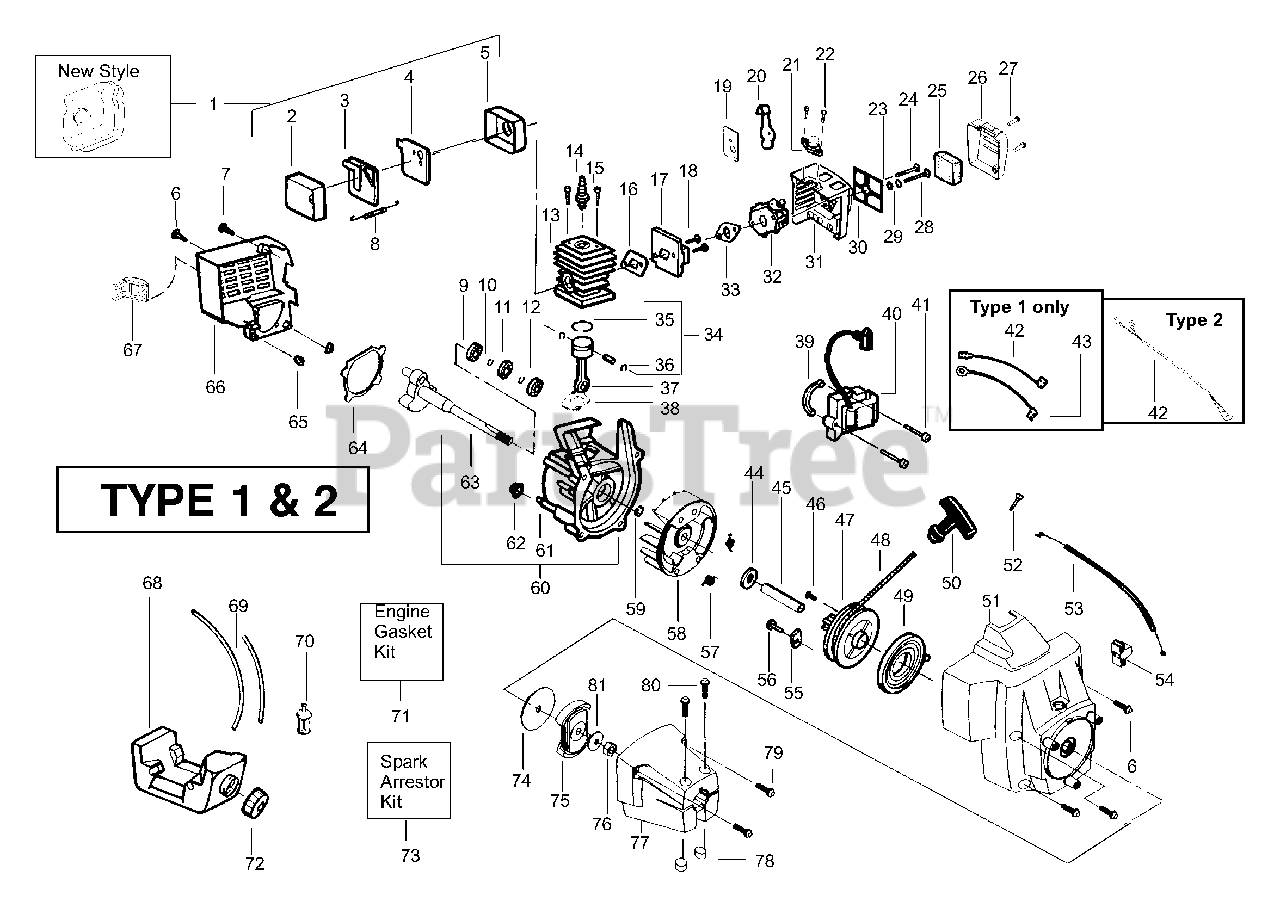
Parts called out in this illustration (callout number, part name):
1	Kit-Muffler Old Style
1	Kit-Muffler New Style
2	Muffler Cover
3	Muffler Baffle-Exit
4	Muffler Baffle-First
5	Muffler Body
6	Screw
8	Muffler Spring Old Style
8	Muffler Spring New Style
9	Inner Bearing
10	Retaining Ring-C'case
11	C'case Seal
12	Outer Bearing
13	Cylinder Kit
14	Spark Plug (RCJ-8Y)
16	Gasket-Cyl/Carb Adpt
17	Kit-Carb. Adaptor
19	Choke Plate
20	Choke Shutter
21	Assy-Purge Bulb
25	Air Filter Foam
26	Air Filter Cover
29	Choke Spacer
30	Filter Plate
32	Assy-Carburetor
33	Gasket-Carburetor
34	Kit-Piston
35	Ring-Piston
36	Piston Pin Retainer
37	assy-Connecting Rod
38	Gasket-Cylinder
39	Spacer-Ign. Module
40	Ignition Module
42	Assy-Lead Wire Old Style (type 1)
42	Assy-Lead Wire New Style (type 2)
43	Assy-Ground Wire Old Style (type 1 only)
45	Spacer-Flywheel
47	Starter Pulley
48	Rope Kit
49	Spring-Starter
50	Handle-Starter
51	Fan Housing Old Style (type 1)
51	Fan Housing New Style (type 2)
53	Assy-Throttle Cable
54	Kit-Switch
55	Retainer
57	Starter Spring
58	Assy-Flywheel
59	Retainer (C'shaft)
60	Assy-C'case & C'shaft
61	Assy-Crankcase Old Style
61	Assy-Crankcase New Style
62	Isolator-Crankcase
63	Assy-Crankshaft
64	Gasket-C'case/Shroud Old Style
64	Gasket-C'case/Shroud New Style
65	Isolator-Shroud
67	Guard-Muffler
68	Assy-Fuel Tank
69	Kit-Fuel Line
70	Assy-Fuel Pickup
71	Kit-Engine Gasket
72	Assy-Fuel Cap
73	Kit-Spark Arrestor Old Style
73	Kit-Spark Arrestor New Style
74	Washer-Clutch
75	Assy-Clutch
77	Assy-Clutch Hsg.
81	Washer-Flat
